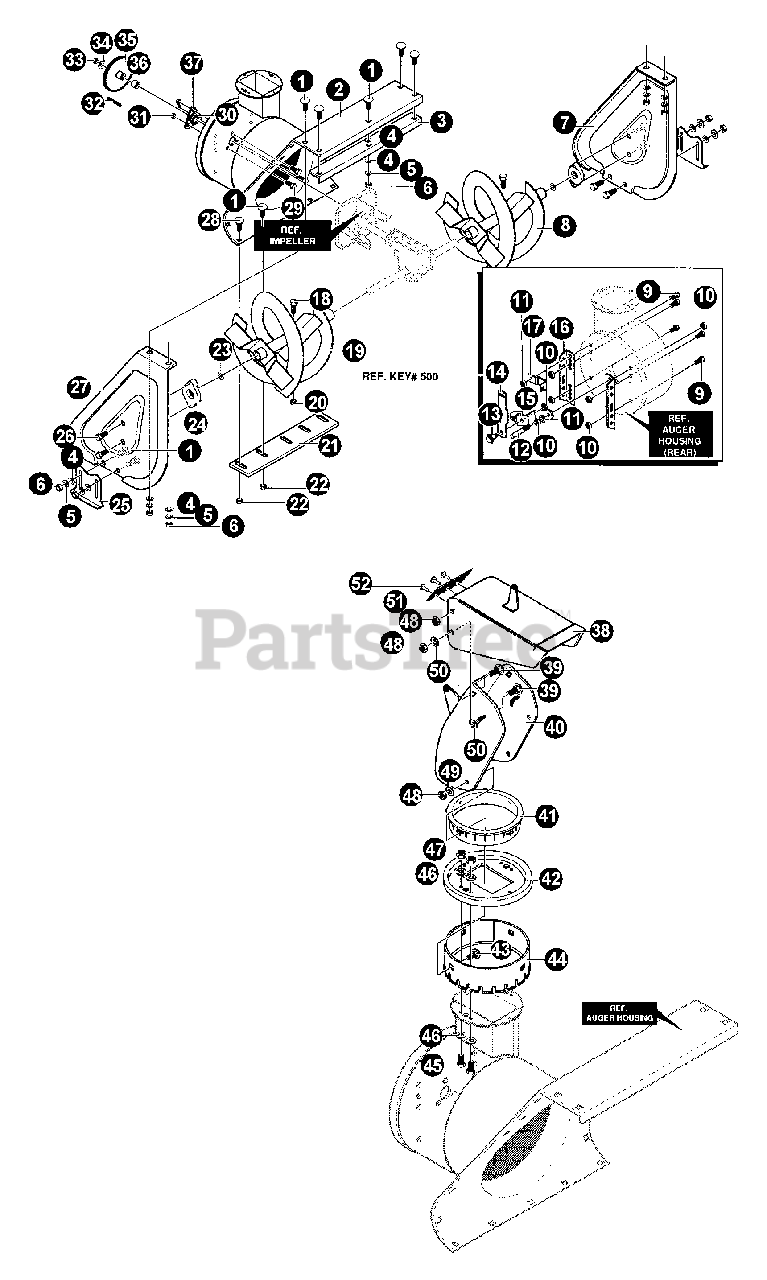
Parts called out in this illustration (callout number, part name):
1	BOLT - 5/16-18 X 3/4"
2	HOUSING, LF
3	STIFFENER, AUGER
4	WASHER
5	LOCKWASHER
6	NUT - 5/16-18
7	CASE, AUGER - LEFT
8	AUGER ASSY - 33"
9	SCREW - 3/8-16 X 3/4"
10	NUT - 3/8-16
11	LOCKWASHER
12	STUD, BRAKE ARM
13	BOLT - 3/8-16
14	BRACKET, IDLER
15	PLATE, CLUTCH
16	BRACKET, CABLE
17	BRACKET, MOUNTING
18	BOLT - 5/16-18
19	AUGER ASSY - 33"
20	NUT - 5/16-18
21	BLADE, SCRAPER LF
22	NUT - 5/16-18
23	WASHER - 1.00X1.31X.035
24	BEARING, AUGER SHAFT
25	SKID, HEIGHT ADJUST
26	SCREW - 5/16-18 X 3/4"
27	CASE, AUGER - RIGHT
28	BOLT - 5/16-18 X 1"
29	SCREW - 5/16-18 X 3/4"
30	BEARING, BALL - 6203
31	NUT - 5/16-18
32	KEY, SQUARE .18SQX88LG
33	LOCKNUT - 1/2-20
34	WASHER - .53X1.00X.063
35	PULLEY, V4L
36	SPACER, SLEEVE .675X1.00X.53
37	RETAINER, BEARING
38	CHUTE - UPPER
39	SCREW - 5/16-18 X 3/4"
40	SCREEN, SPARK ARRESTOR
41	RETAINER, RING INNER
42	COLLAR
43	BOLT, 5/16-18X1.00 CARRLN
44	RETAINER, RING OUTER
45	SCREW - 1/4-20
46	WASHER
47	NUT - 1/4-20
48	NUT - 5/16-18
49	WASHER
50	WASHER - PLASTIC
51	SKIRT, CHUTE EXTENSION
52	RIVET - POP
